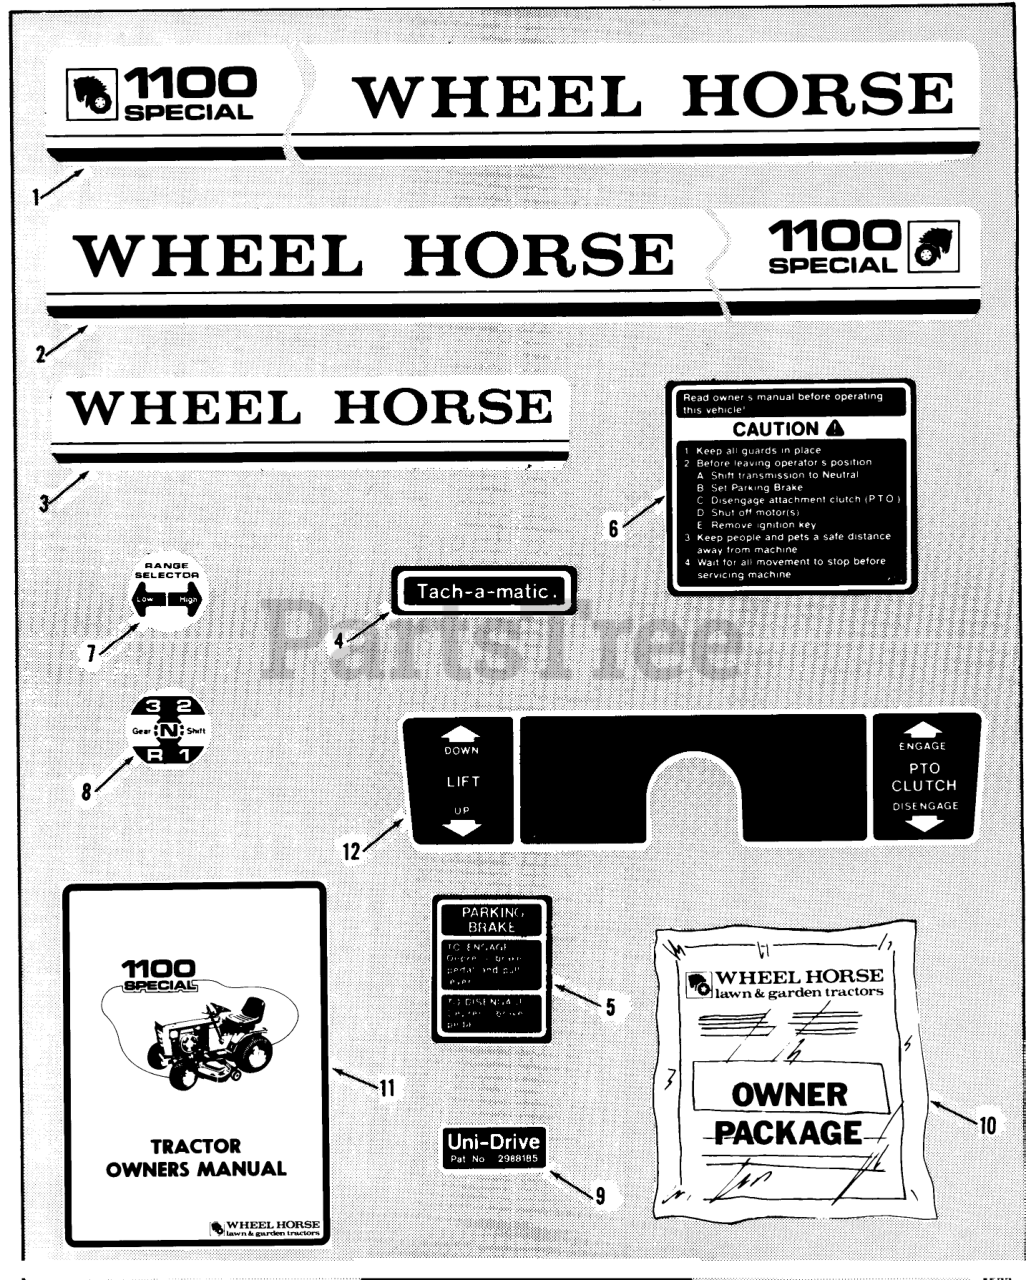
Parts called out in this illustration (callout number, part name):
1	Decal LH 1100 Special
2	Decal RH 1100 Special
3	Decal-Rear
4	DECAL-TACHAMATIC
5	DECAL-PARKING BRAKE
6	DECAL-CAUTION
7	DECAL HI-LO
8	DECAL-SHIFT
9	Decal-Unidrive
10	Loose Parts Package
11	Tractor Owner-s Manual
12	Decal-Control Housing
